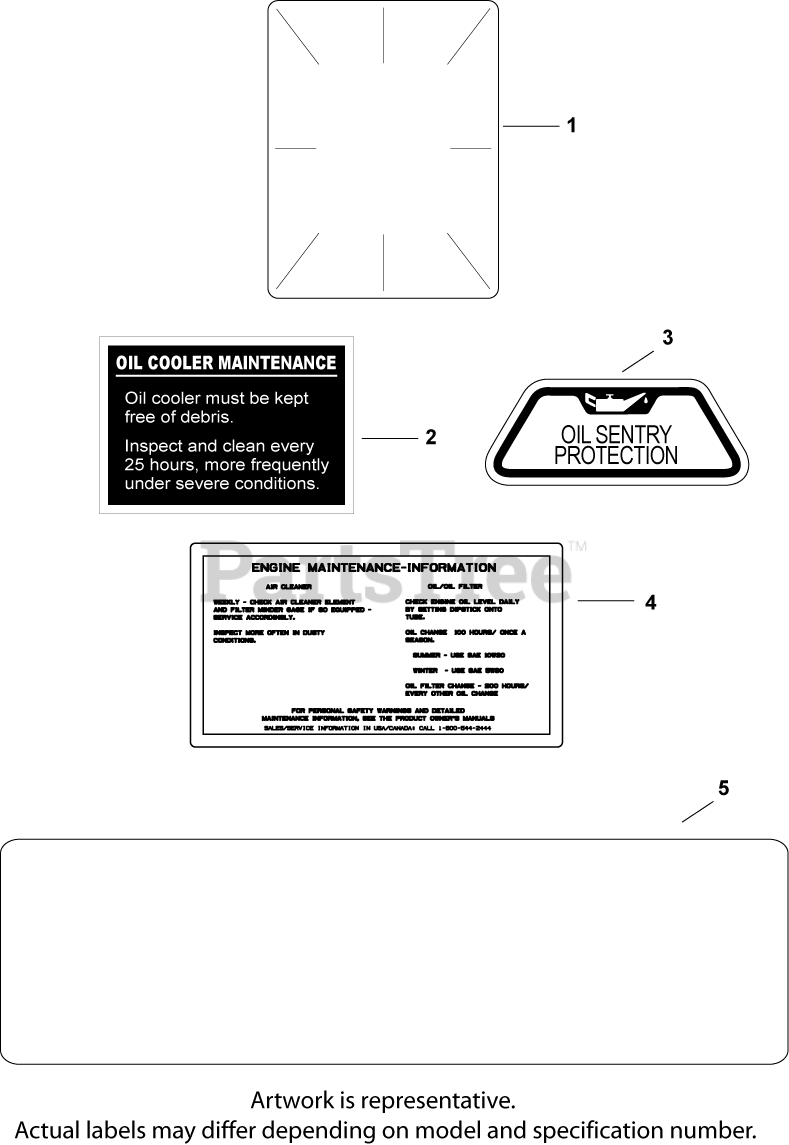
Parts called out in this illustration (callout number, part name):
1	DECAL, CLEAR LAMINATE USE 25 113 70-S
2	DECAL, OIL COOLER - (#DSC)
3	DECAL, OIL SENTRY - (#DSC)
4	DECAL, AIR CLEANER - (#DSC)
5	DECAL, 25 HP
